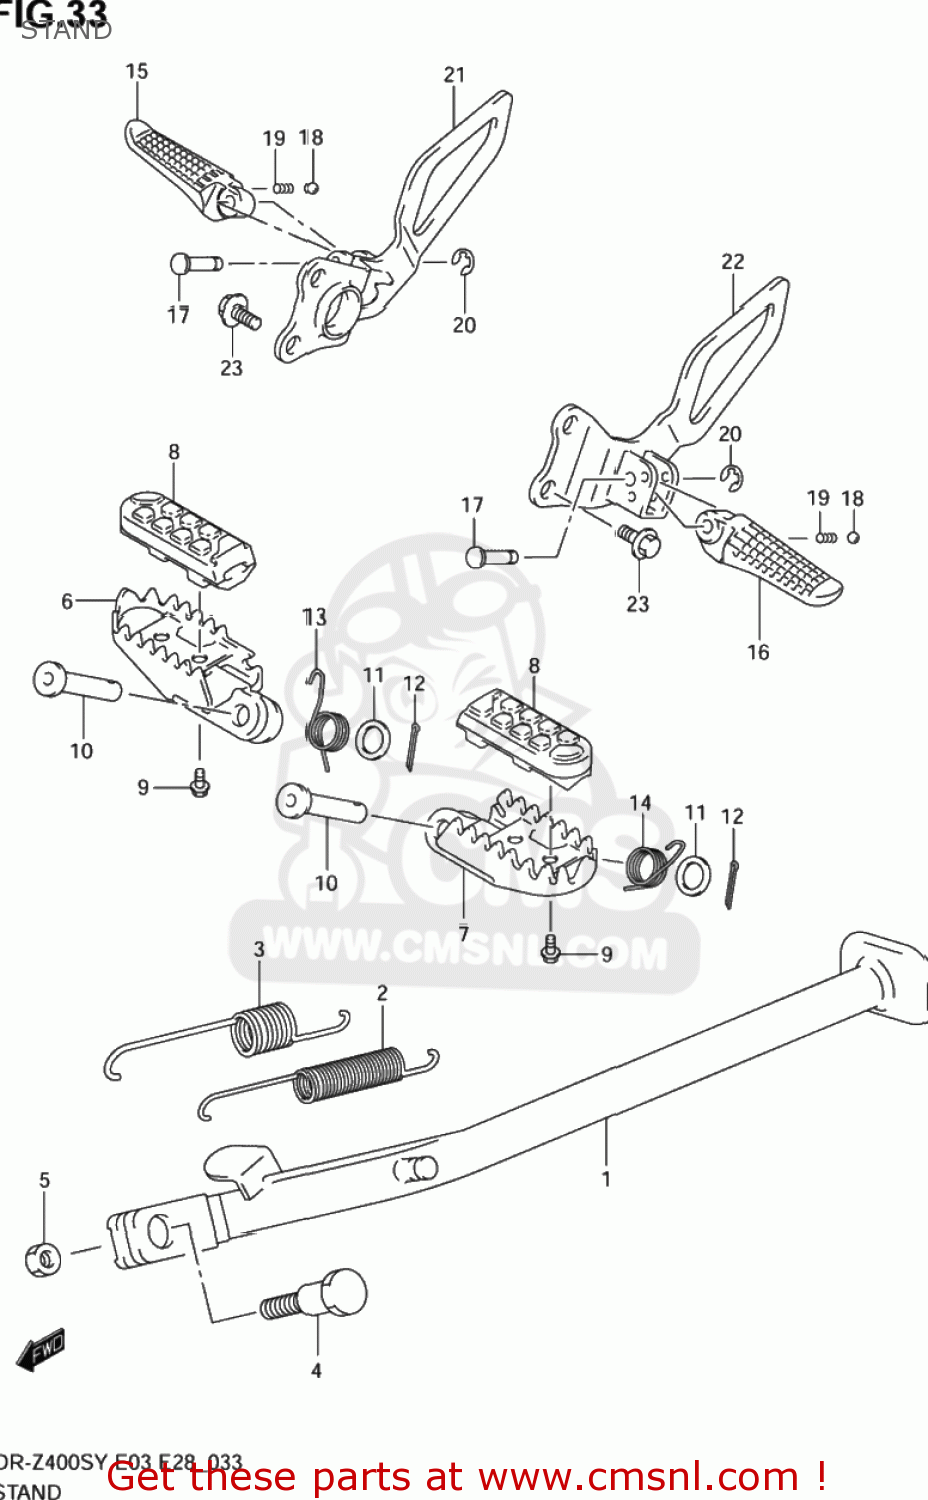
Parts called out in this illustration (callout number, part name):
1	STAND,PROP
2	SPRING
3	SPRING
4	BOLT(10X33)
5	NUT,PROP STAND
6	FOOTREST,R
7	FOOTREST,L
8	RUBBER,FOOTREST
9	BOLT
10	PIN(10X41.5)
11	WASHER
12	PIN 25X20
13	SPRING
14	SPRING
15	BAR,PILLION FOOTREST,R
16	BAR,PILLION FOOTREST,L
17	PIN
18	BALL
19	SPRING
20	E-RING
21	BRACKET,PILLION,R
22	BRACKET,PILLION,L
23	BOLT
